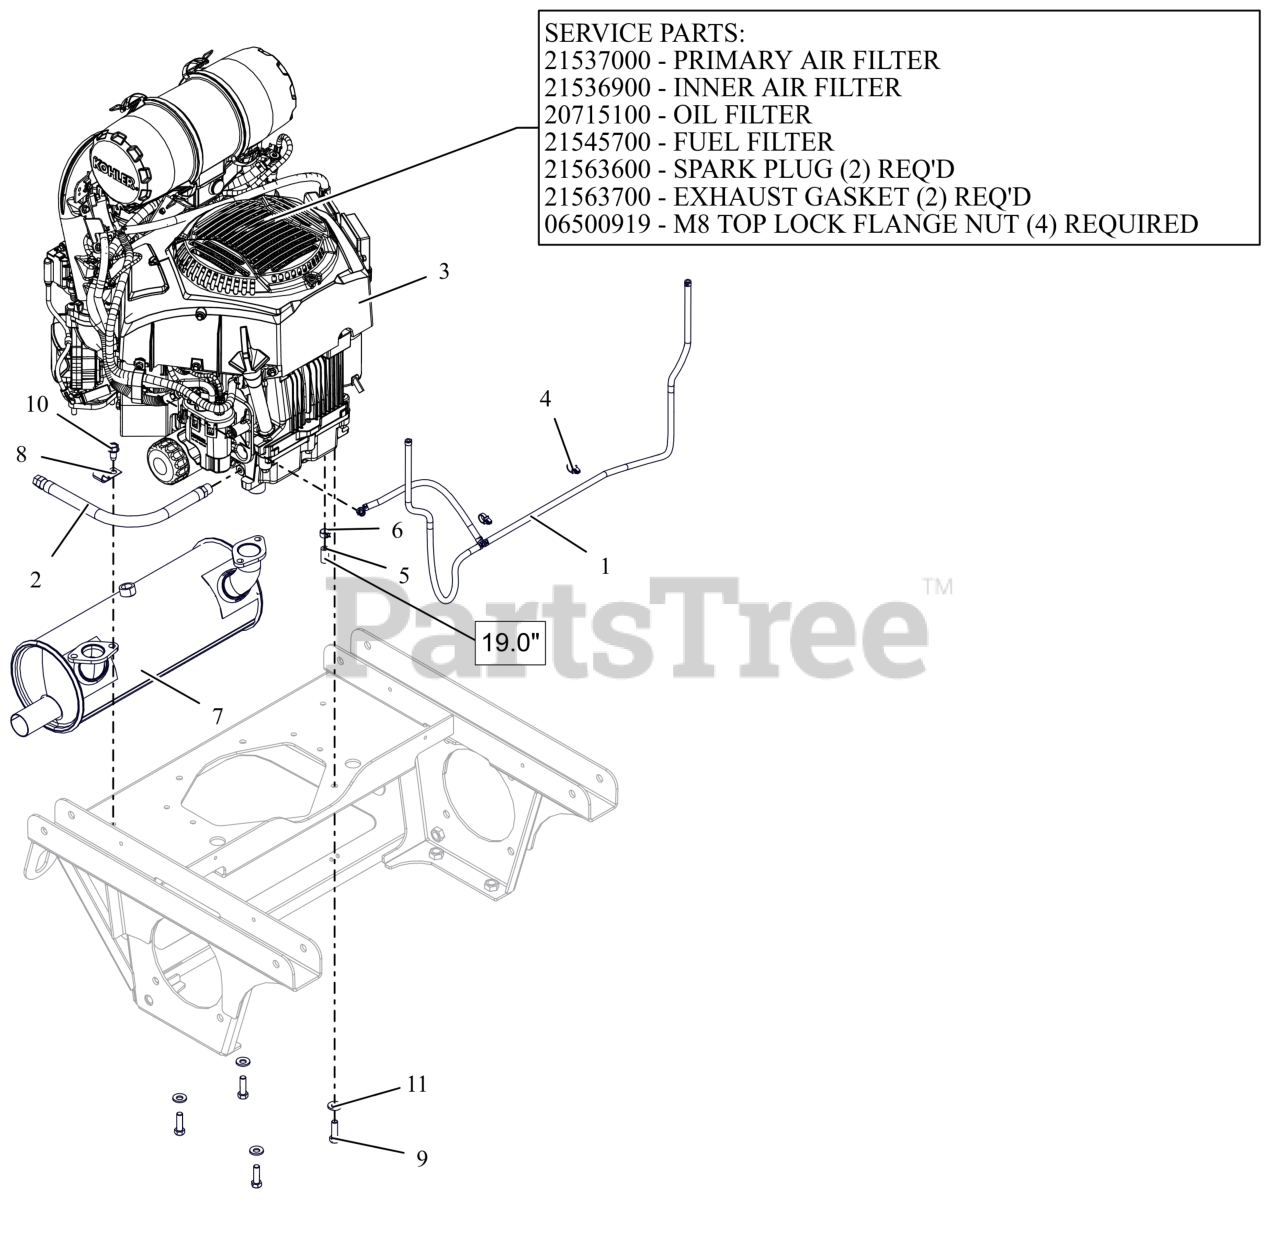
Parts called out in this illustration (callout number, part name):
1	ASM, KOHLER EFI VAPOR LINE
2	HOSE, OIL DRAIN
3	ENGINE, KOHLER EFI
3	ELEMENT, OUTER PRIMARY
3	ELEMENT, INNER SAFETY
3	OIL FILTER KOHLER
3	FILTER-FUEL KOHLER COURAGE PRO
3	PLUG, SPARK
3	GASKET, EXHAUST
3	NUT-LK-TOP-FLG M8 ZCC
4	ROUTING CLIP (1/2" ID)
5	HOSE, .25 LOW-PERM BULK GAS
6	CLAMP, FUEL LINE
7	MUFFLER, KOHLER EFI
9	BLT, HEX .38-16X1.25 G5 ZCC NT
10	SCR,TAP .375-16X.75 HWH TR ZCC
11	WASHER, 3/8" SPRING DISC
